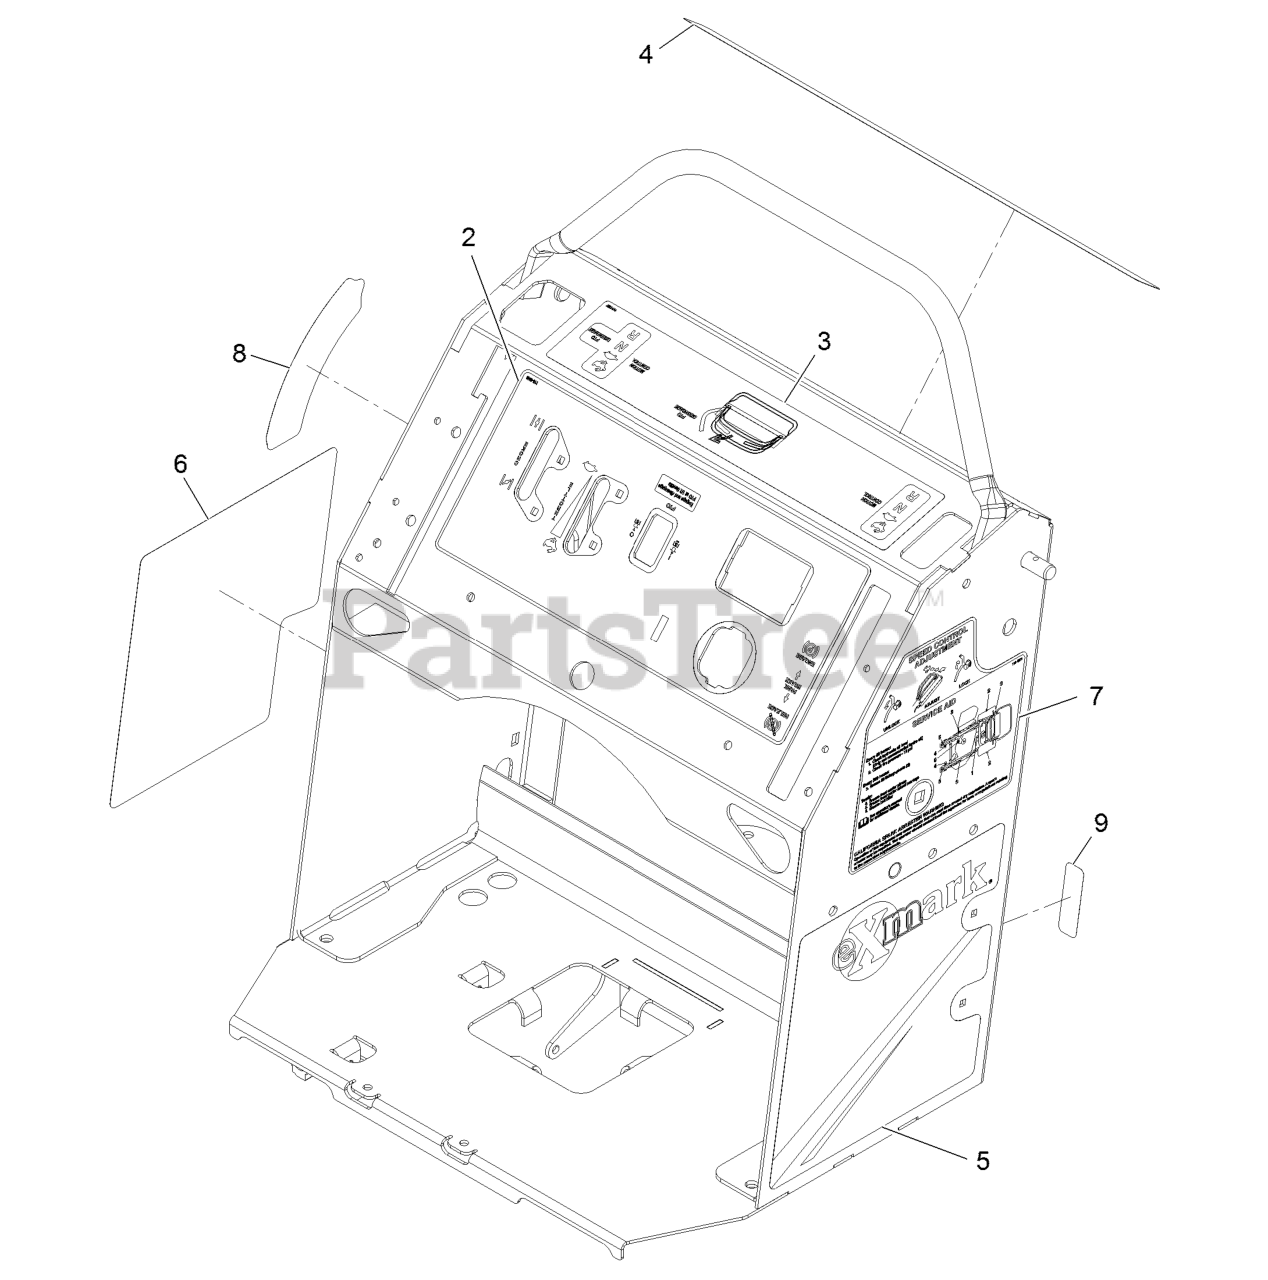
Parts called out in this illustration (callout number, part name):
2	DECAL-CONTROL PANEL
3	DECAL-MOTION CONTROL
4	DECAL-WARNING
5	DECAL-LH PANEL
6	DECAL-RH PANEL
7	DECAL-SERVICE AID
8	DECAL-HEIGHT OF CUT
9	DECAL-FUSE
